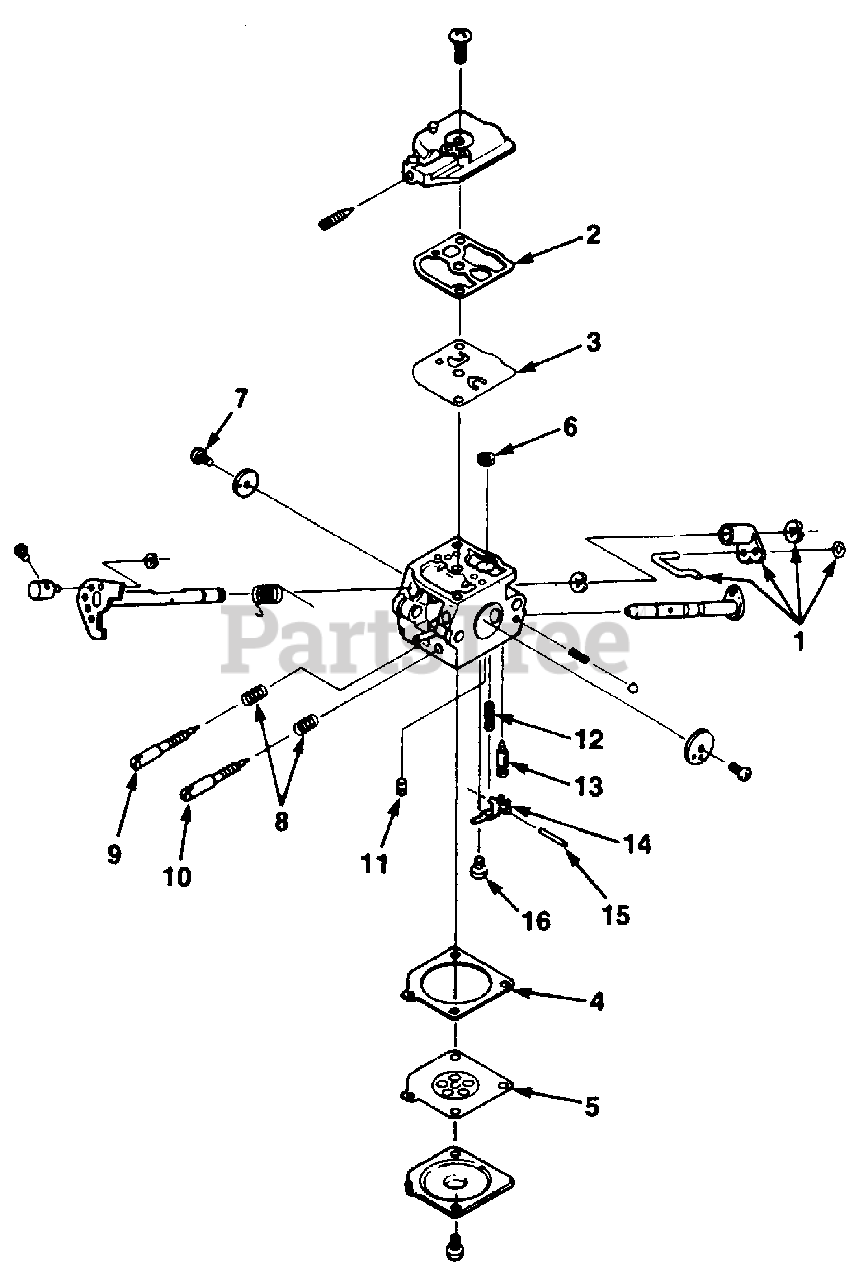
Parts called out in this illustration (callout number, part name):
1	Superseded by UP07106
2	REPAIR KIT (250)
3	REPAIR KIT (250)
4	REPAIR KIT (250)
5	REPAIR KIT (250)
6	REPAIR KIT (250)
7	REPAIR KIT (250)
8	REPAIR KIT (250)
9	REPAIR KIT (250)
10	REPAIR KIT (250)
11	REPAIR KIT (250)
12	REPAIR KIT (250)
13	REPAIR KIT (250)
14	REPAIR KIT (250)
15	REPAIR KIT (250)
16	REPAIR KIT (250)
